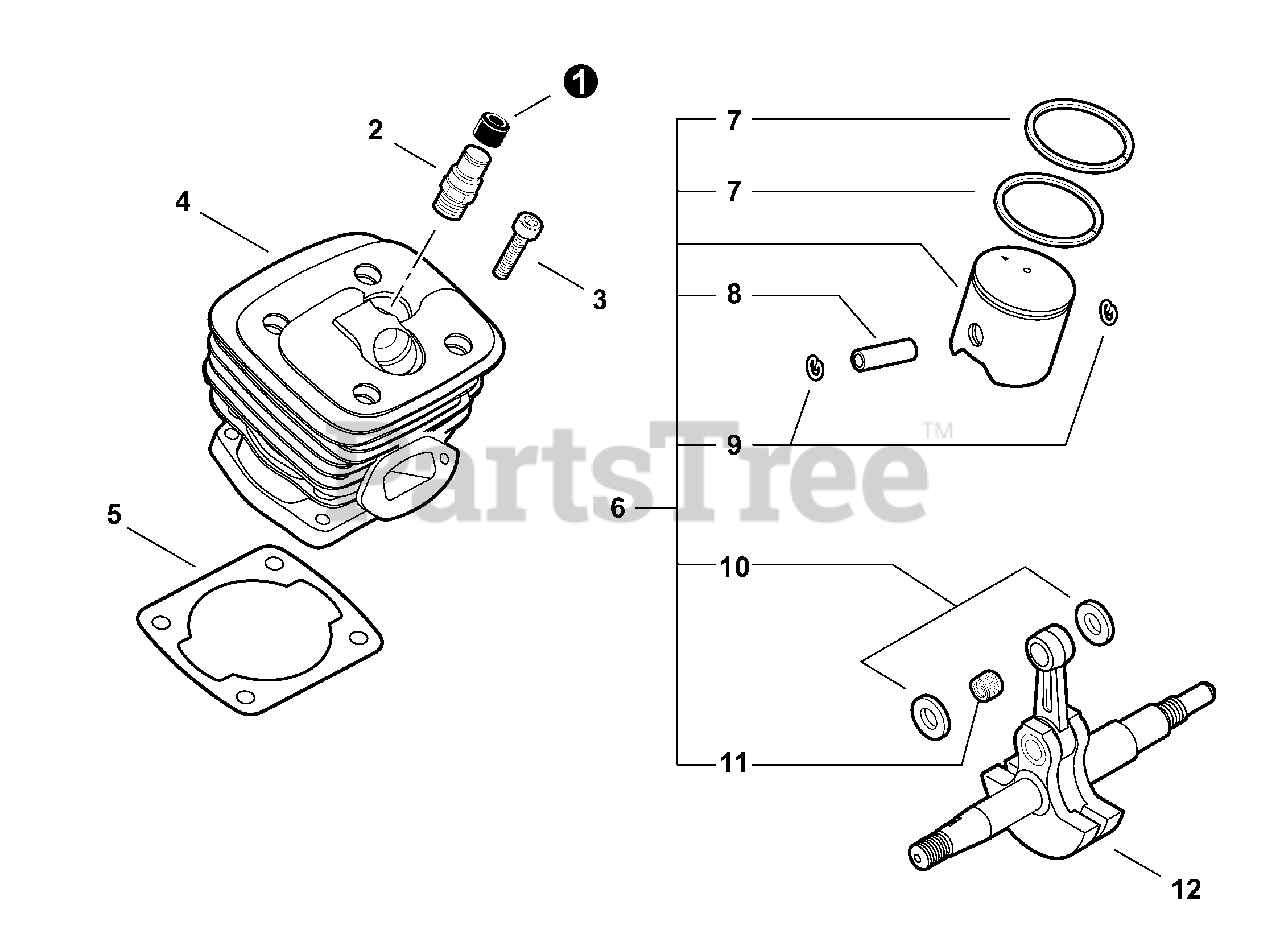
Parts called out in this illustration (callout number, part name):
1	GROMMET,PLUG
2	DECOMP,ASM
3	BOLT, TORX 5
4	CYLINDER
5	GASKET,CYL
6	PISTON KIT
7	RING, PISTON
8	PIN,ENG 11
9	RING,END
10	WASHER,CIRCULAR 11
11	BEARING,NEEDLE 11
12	CRANKSHAFT,ASY
